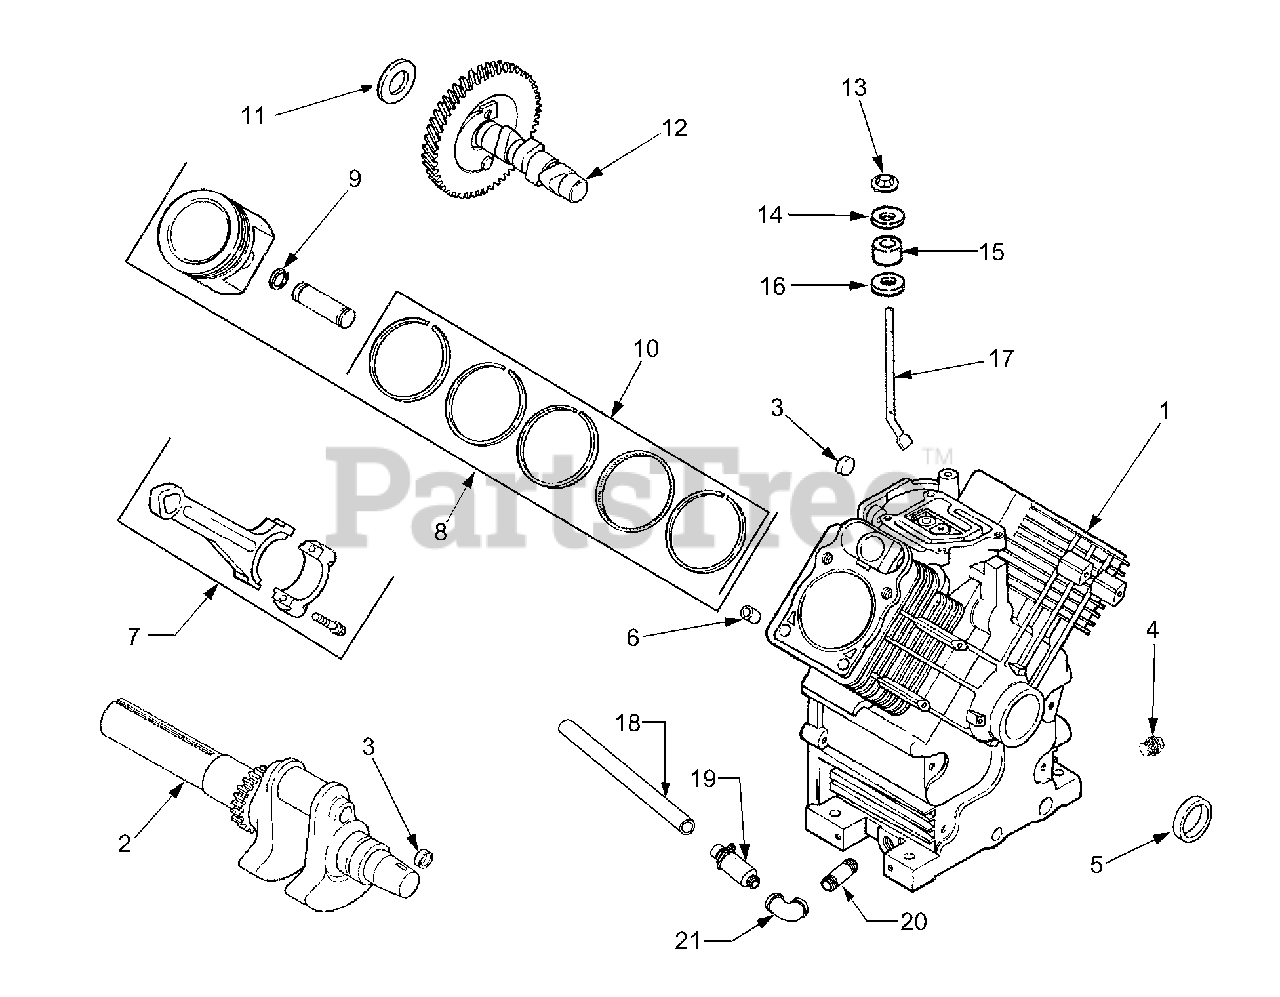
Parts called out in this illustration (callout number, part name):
1	Engine, Complete
2	Crankshaft
3	Plug, Cup
4	Plug, Hex Head, 3/8 NPTF
5	Seal, Oil
6	Pin, Dowel Locating
7	Rod, Connecting
8	Piston w/Ring Set
9	Retainer, Piston Pin
10	Ring Set
11	Shim, Camshaft, .0320
12	Camshaft
13	Ring, Retainer
14	Washer, Nylon
15	Seal, Governor Cross Shaft
16	Washer, Plain
17	Shaft, Governor Cross
18	Hose, Oil Drain
19	Drain, Oil
20	Pipe, Straight
21	Elbow, 90°.
